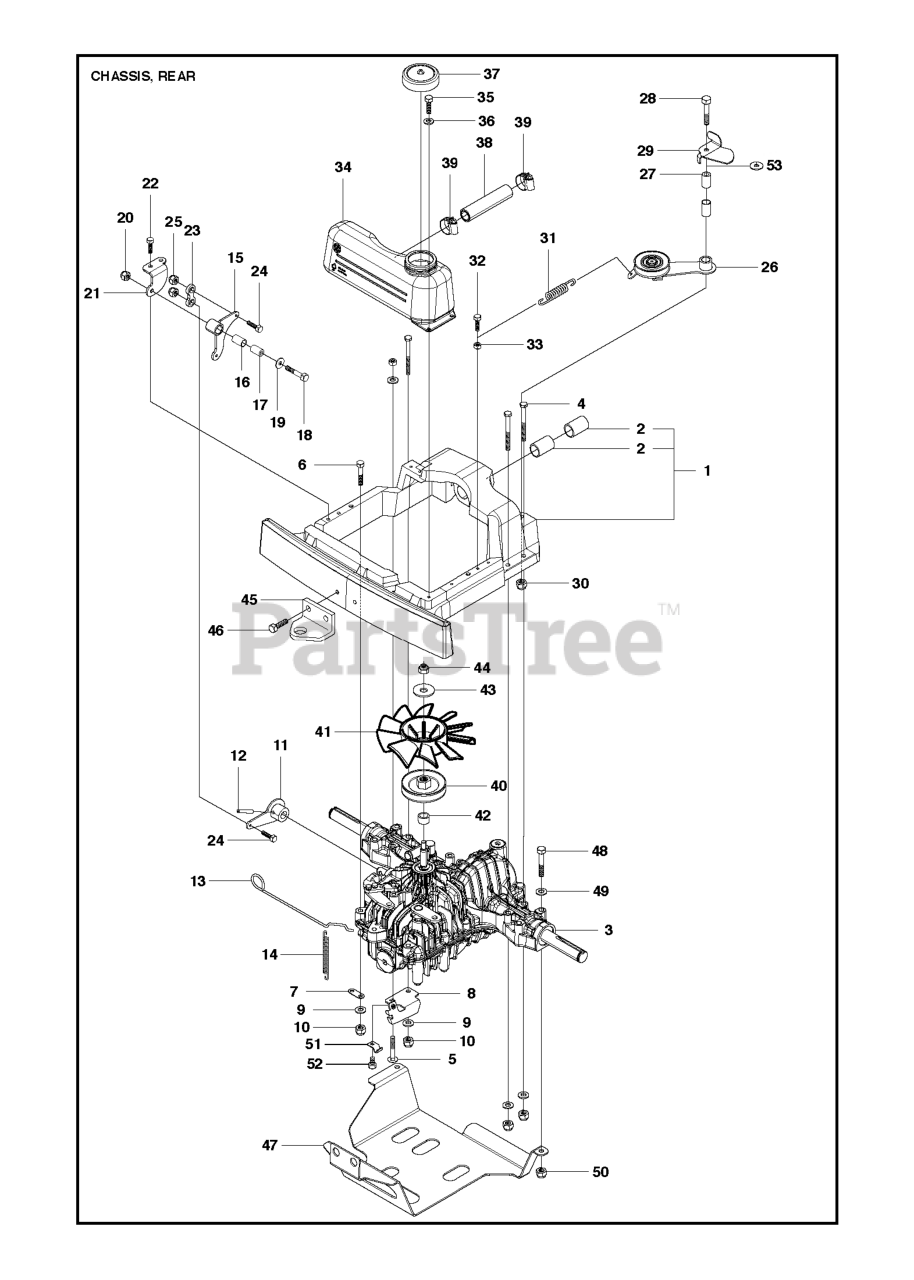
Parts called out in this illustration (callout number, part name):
9	WASHER BRB 8.4X17
10	LOCKNUT M8
18	SCREW
20	LOCKNUT M8
22	REPL BY 725 24 49-51
24	SCREW M6S 5X20
25	LOCKNUT M5
30	LOCKNUT M8
34	EXPANSION TANK K664
35	BOLT FLANGE - M6X20
36	WASHER - 26X6.5X1.6
44	NUT
46	Screw M10x25
49	WASHER BRB 8.4X17
50	LOCKNUT M8
51	CLAMP
52	Screw
53	SPACER
